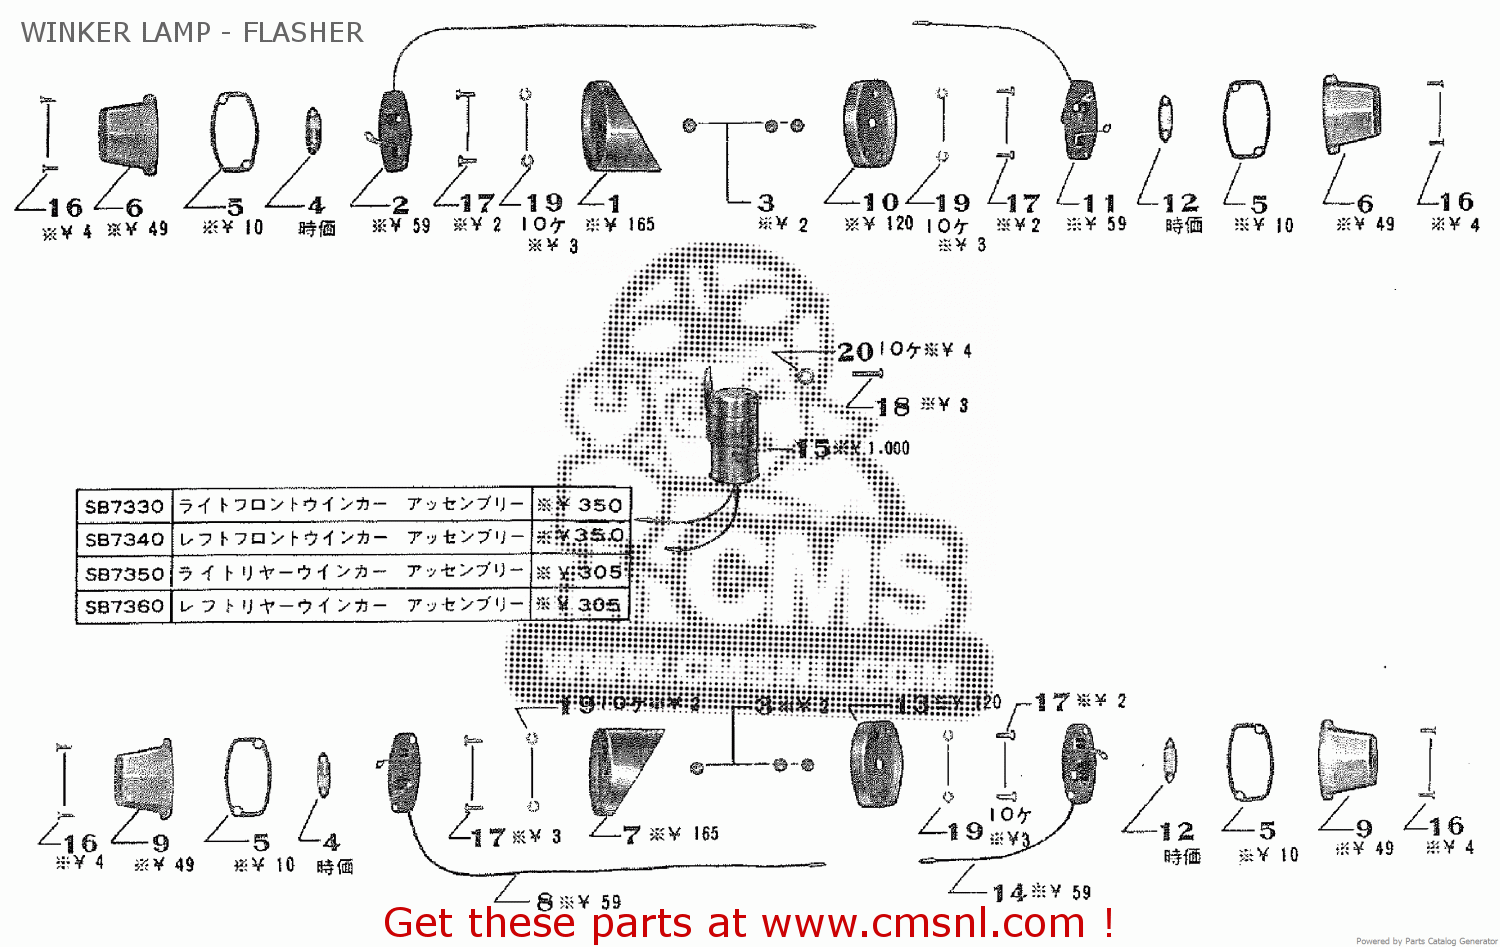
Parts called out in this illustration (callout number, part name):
1	RIGHT FRONT WINKER BODY
2	RIGHT FRONT WINKER LAMP BASE COMP
3	WINKER LAMP BASE RUBBER BUSH
4	FRONT WINKER LAMP VALVE
5	WINKER LENS PACKING
6	RIGHT WINKER LENS
7	LEFT FRONT WINKER BODY
8	LEFT FRONT WINKER LAMP BASE COMP
9	LEFT WINKER LENS
10	RIGHT REAR WINKER BODY
11	RIGHT REAR WINKER LAMP BASE COMP
12	REAR WINKER LAMP VALVE
13	LEFT REAR WINKER BODY
14	LEFT REAR WINKER LAMP BASE COMP.
15	FLASHER ASSY.
16	4X12 CROSS SCREW
17	5X12 CROSS SCREW
18	6X15 CROSS SCREW
19	5MM SPRING WASHER
20	6MM SPRING WASHER
